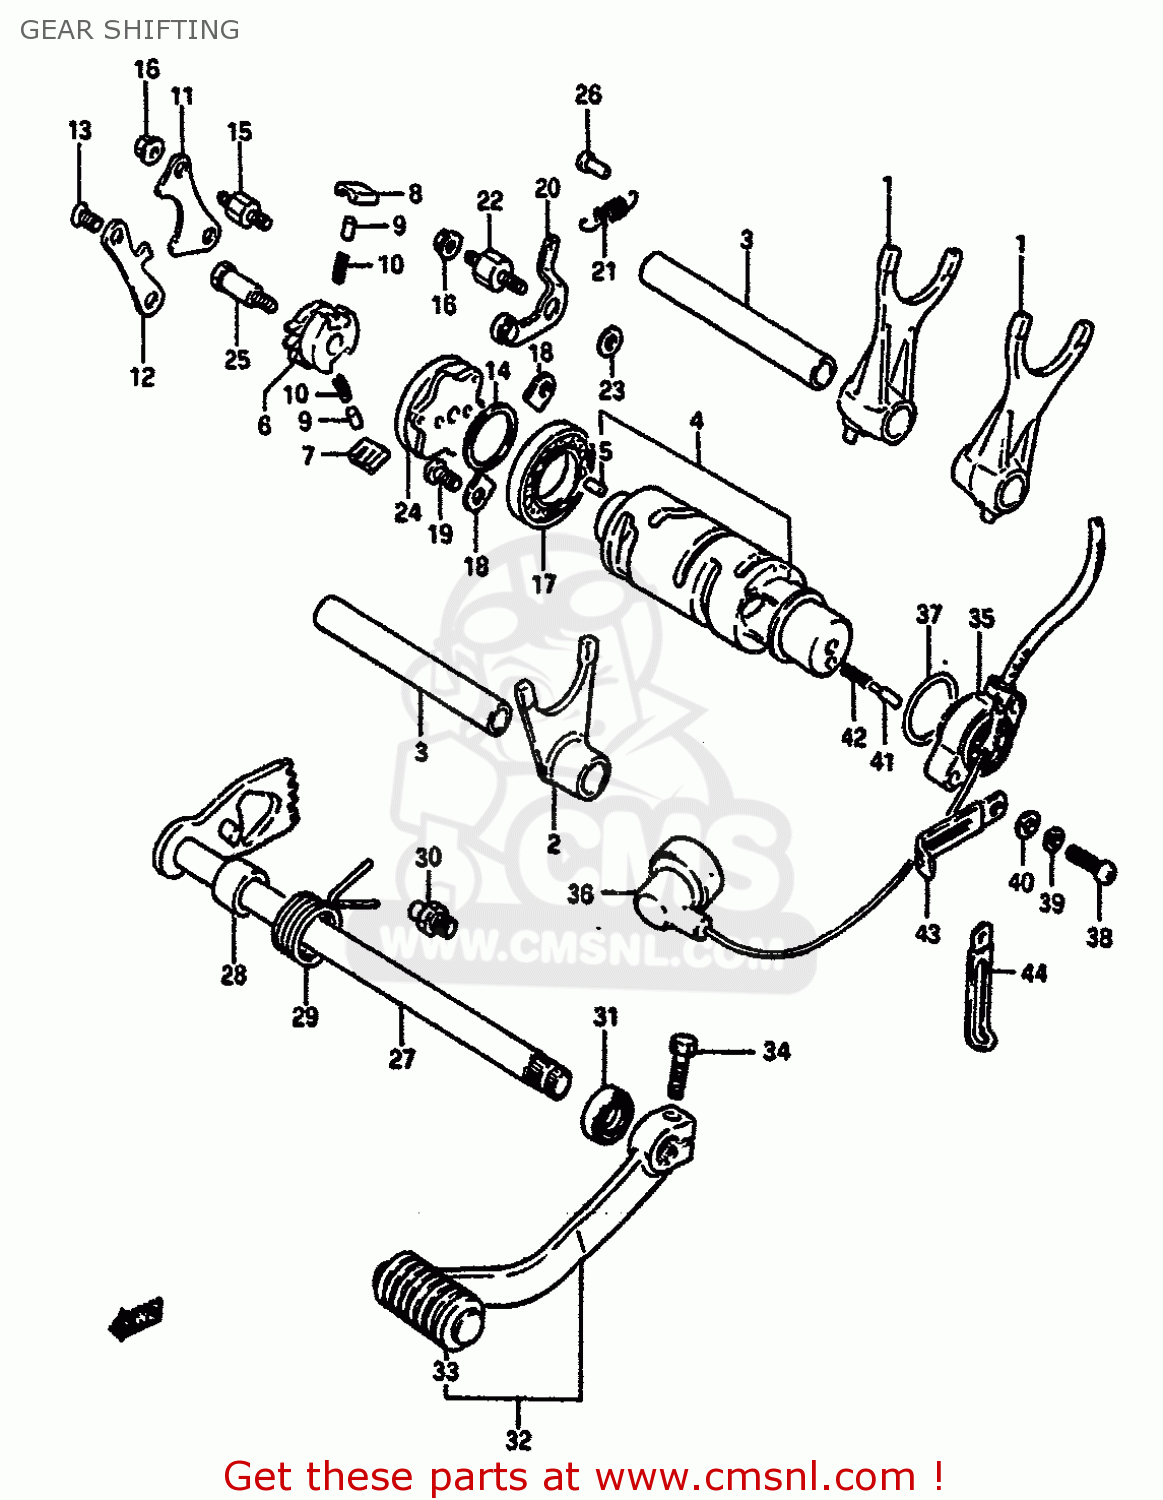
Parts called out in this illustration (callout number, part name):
1	FORK,GEAR SHIFT NO.1
2	FORK,GEAR SHIFT NO.2
3	SHAFT,GEAR SHIFT FORK(L:115)
4	CAM,GEAR SHIFT
5	PIN
6	GEAR,GEARSHIFT CAM DRIVE
7	PAWL,GEAR SHIFT NO.1
8	PAWL,GEAR SHIFT NO.2
9	PIN(5X8)
10	SPRING
11	LIFTER,GEAR SHIFT POLE
12	GUIDE,GEAR SHIFT CAM
13	SCREW
14	WASHER(25X32X3)
15	BOSS,SHIFT PAWL LIFTER
16	NUT
17	BEARING
18	RETAINER,SHIFT CAM,R BEARING
19	SCREW 6X12
20	STOPPER,GEAR SHIFT CAM
21	SPRING
22	SUPPORT,CAM STOPPER ARM
23	WASHER
24	PLATE,GEAR SHIFT CAM
25	PIN,SHIFT CAM DRIVEN GEAR
26	HOOK
27	SHAFT,GEAR SHIFT
28	SPACER(12X20X15.3)
29	SPRING
30	STOPPER,GEAR SHIFT CAM
31	OIL SEAL
32	LEVER ASSY,GEAR SHIFT
33	RUBBER,GEAR SHIFT PEDAL
34	BOLT
35	BODY,SWITCH
36	CAP,OIL PRESSURE SWITCH
37	O RING(D:2.4,ID:26.2)
38	SCREW 5X20
39	LOCK WASHER
40	WASHER
41	PIN(5X15.5)
42	SPRING
43	CLAMP
44	CLAMP
